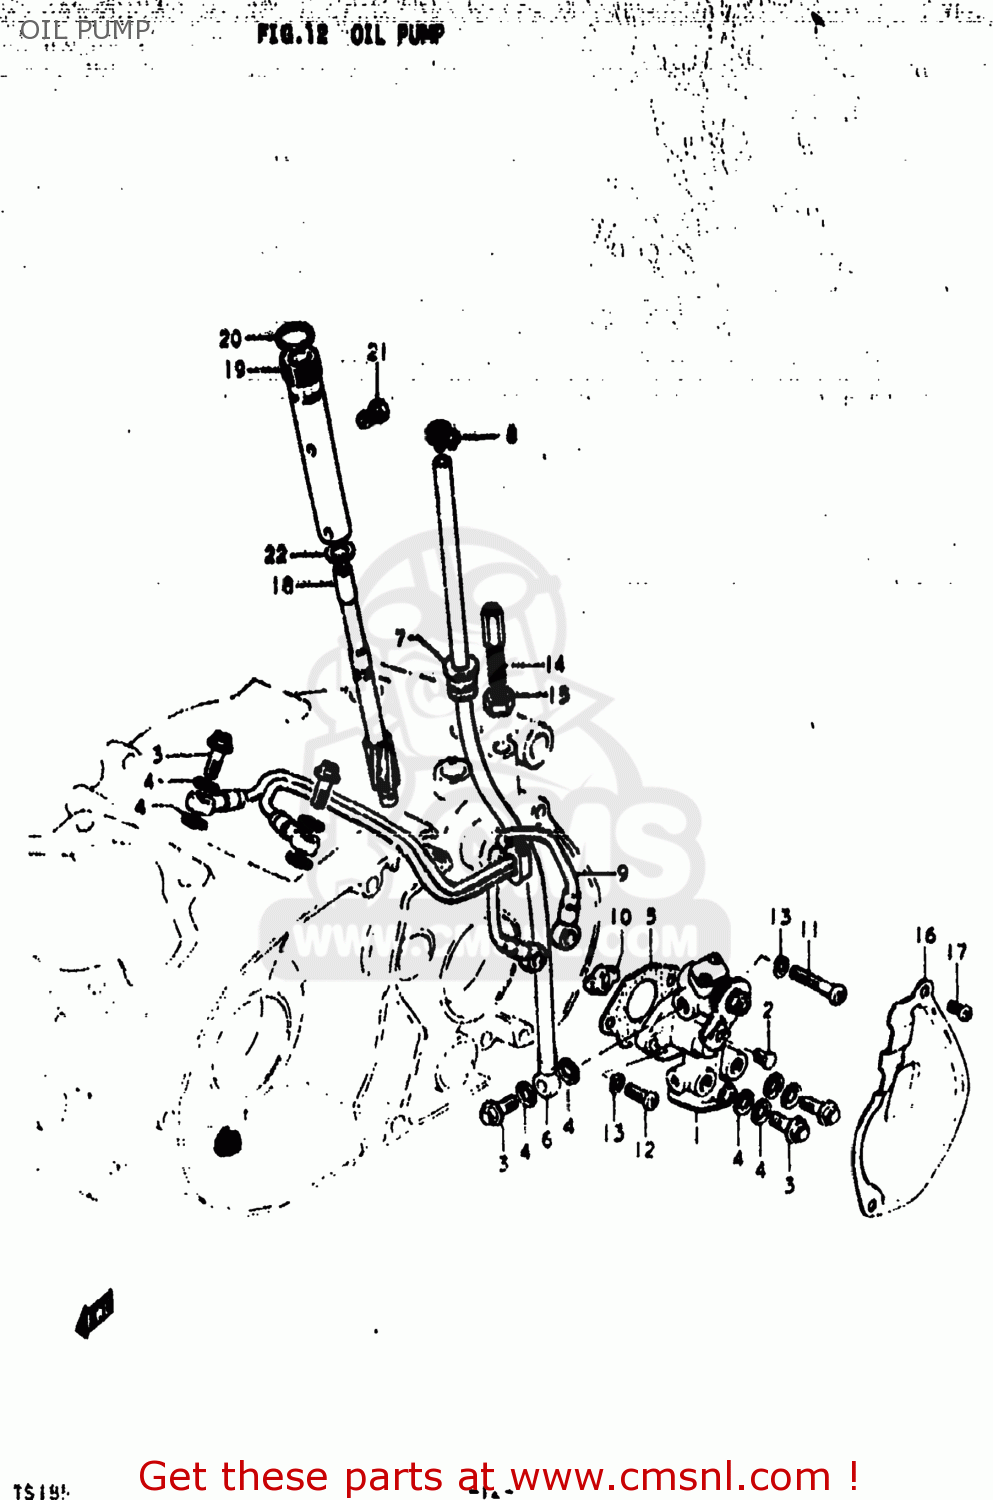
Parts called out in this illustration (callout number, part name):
1	PUMP ASSEMBLY,OIL
2	TERMINAL,CABLE
3	UNION BOLT
4	GASKET (NAS)
5	GASKET,OIL PUMP (MCA)
6	HOSE,OIL NO.1
7	BUSHING
8	CLAMP
9	HOSE,OIL NO.2
10	PIECE,OIL PUMP DRIVE
11	SCREW
12	SCREW
13	LOCK WASHER
14	BOLT
15	NUT
16	CAP,OIL PUMP INSPECTION
17	SCREW
18	GEAR,TACHOMETER DRIVEN
19	SLEEVE,TACHOMETER DRIVE
20	O RING(D:1.3,ID:9.6)
21	BOLT(6X12)
22	WASHER(8X13.7X1)
